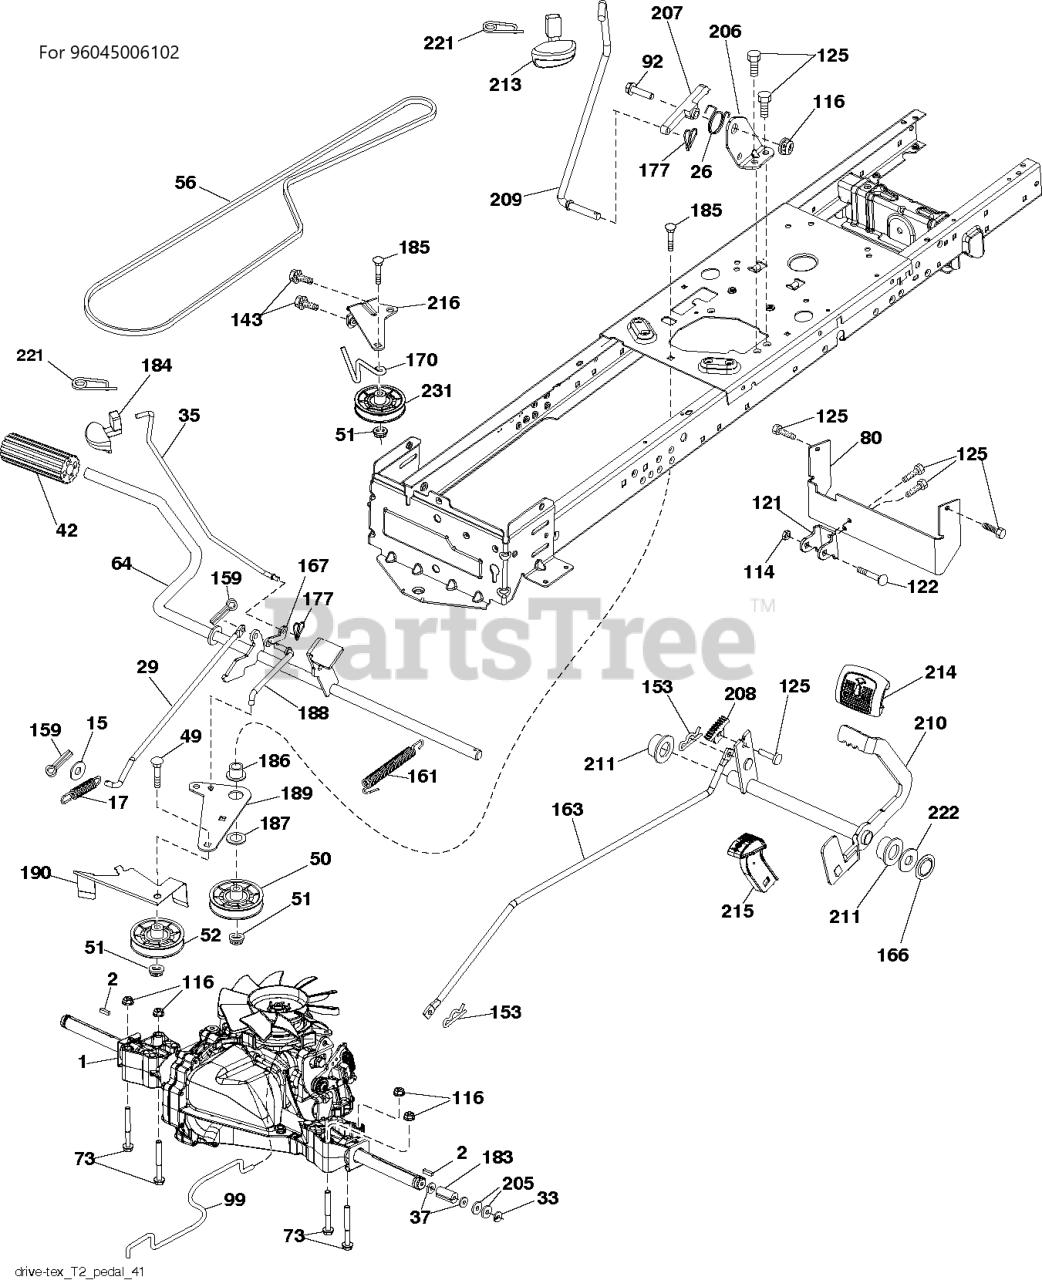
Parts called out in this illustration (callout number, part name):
2	SQUARE KEY
15	WASHER PLAIN WASHER 3/8 X 0.08
17	SPRING.BRAKE.HG3000/3500
26	SPRING.RETURN.CRUISE
29	ROD.BRAKE.T2.TEX
35	ROD ROD.PARKINGBRAKE.GT.HUSQ/P
42	PEDAL COVER
50	IDLER.FLAT.910.OFFSET
51	NUT LOCK FLG 3/8-16 UNC
52	IDLER.V-GROOVE.910.OFFSET
56	BELT.GROUND.DRIVE.T2-HP.CE
64	SHAFT.ASM.PEDAL.BRK.CNTR
80	STRAP.TORQUE.T2
99	ROD.ASM.BYPASS.SPRING.T2.FS
121	BRACKET STRAP TORQUE
122	BOLT.5/16-18X2.5
125	SCREW
153	RETAINER M
161	SPRING, RETURN LT
166	NUT.PUSH.625
167	LATCH.BRAKE.SPRING
170	KEEPER.CENTER SPAN.1.688
177	PIN COTTER;LOCKING;BOWTIE;1IN
183	SPACER, AXLE PVST
184	HANDLE.PARKING.BRAKE.H (BLK)
186	SPACER.RETAINER
188	LINK.CLUTCH.GROUND DRIVE.LONG
189	BELLCRANK.GROUND.DRIVE.TEX.
190	KEEPER.BELLCRANK.DRIVE
206	BRACKET.MOUNT.CRUISE.LATCH
209	ROD ROD.CRUISECONTROL.GT.HUSQ/
210	ROCKER.ASM.PEDAL.CONTR
211	BEARING.NYLON
213	KNOB.CONTROL.CRUSIE.HU
214	PEDAL.FORWARD.PAD.TEX
215	PEDAL.COVER.REVERSE.CRD.X428BK
216	BRACKET.PULLEY.IDLER.W/TEX
221	RETAINER.SPRING.CLIP.H
222	WASHER 21/32 X 1-1/4 X 10 GA.
231	IDLER.V-GROOVE.1.688.OFFSET
